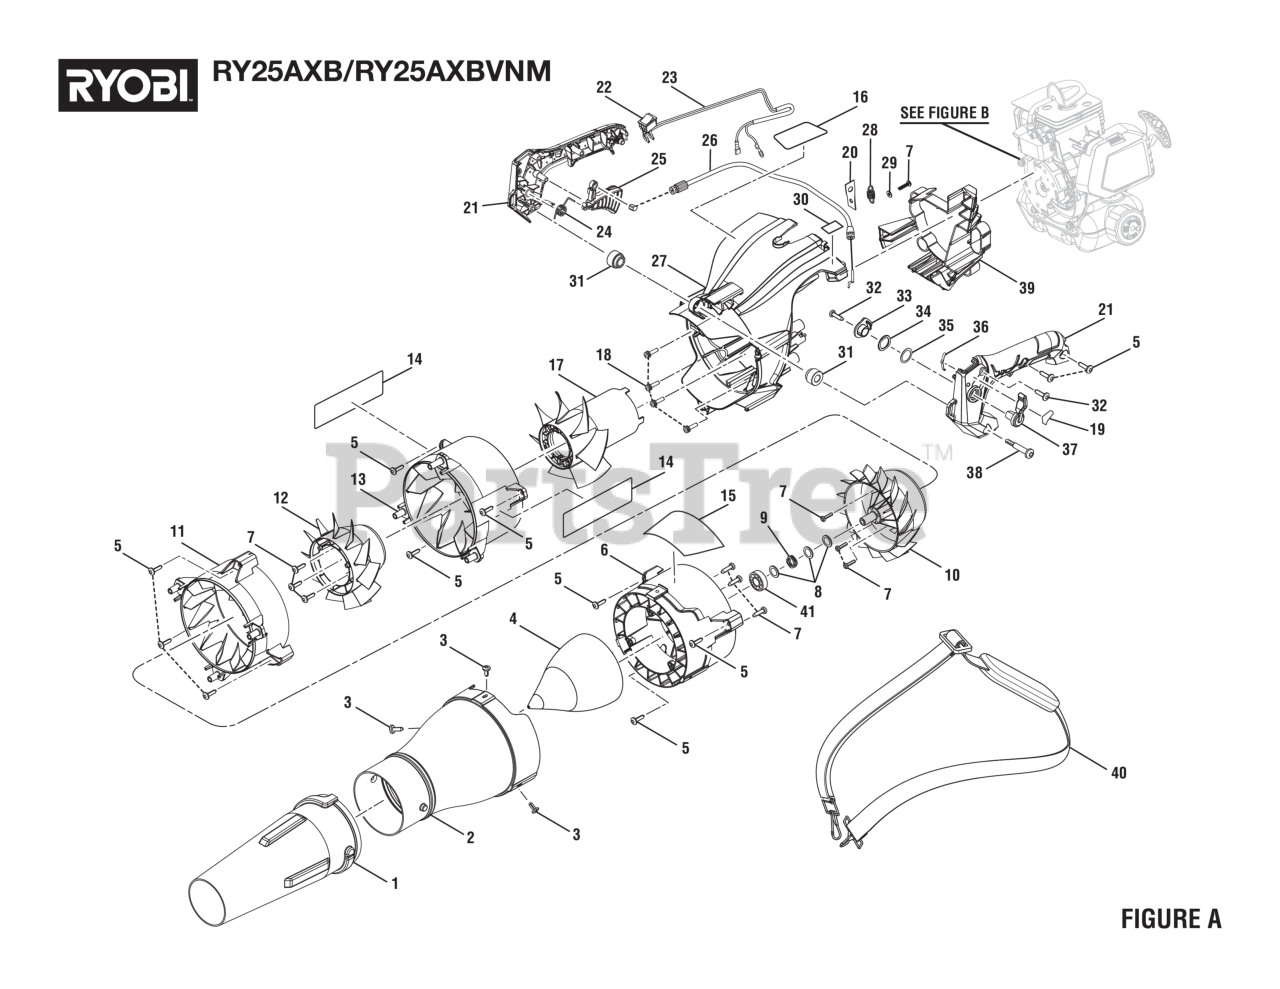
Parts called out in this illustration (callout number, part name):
1	Blower End Nozzle
2	Reducer Nozzle
3	Vacuum Tube Screw (10-14 x 1/2 in., T25 Torx Truss Hd. T.F.)
4	Reducer Cone
5	Screw (10-14 x 19 mm, T25 Torx Truss Pan Hd. T.F.)
6	Axial Stator w/Bearing Assembly Stage 3
7	Screw (M4 x 1.41 mm x 18 mm, T20 Torx Pan Hd. T.F)
8	Washer (OD18 x ID12.15 x 1.5t)
9	Wave Spring
10	Axial Fan (Stage Three)
11	Axial Stator (Stage 2)
12	Axial Fan (Stage Two)
13	Axial Stator (Stage 1)
14-A	Jet Fan Logo Label
14-B	Jet Fan Label
15-A	Logo Label (Full Crank, 2 cycle)
15-B	Logo Label (Full Crank, 2 cycle)
16	Warning Icon Label
17	Axial Fan (Stage 1)
18	Cap Screw w/Washer (M5 x 16 mm, T25 Torx Soc. Hd.)
19	Cruise Lever Position Label
21	Handle Assembly
22	Stop Switch (Momentary Contact)
23	Wiring Harness w/Fiber Sleeve
24	Torsion Spring (Throttle Trigger)
25	Throttle Trigger
26	Throttle Cable
27	Intake Housing (Inc. Key Nos. 16 and 30)
28	Isolator Spring
29	Flat Washer (OD10 x ID42 x 1t)
30	Primer Bulb Location Label
31	Bushing (Front Isolator)
32	Screw (#10-14 x 3/4 in, T25 Torx Pan Hd. T.F.)
33	Throttle Actuator (Cruise Control)
34	Wavy Washer (217OD x 165ID x 15t)
35	Washer (22.5OD x 16ID x 0.5t)
36	Detent Spring
37	Cruise Control Lever
38	Shoulder Screw (M5 x 40 mm, T25 Torx Truss Hd. T.F.)
39	Intake Guard
40	Shoulder Strap
41	Ball Bearing (6001-zz)
